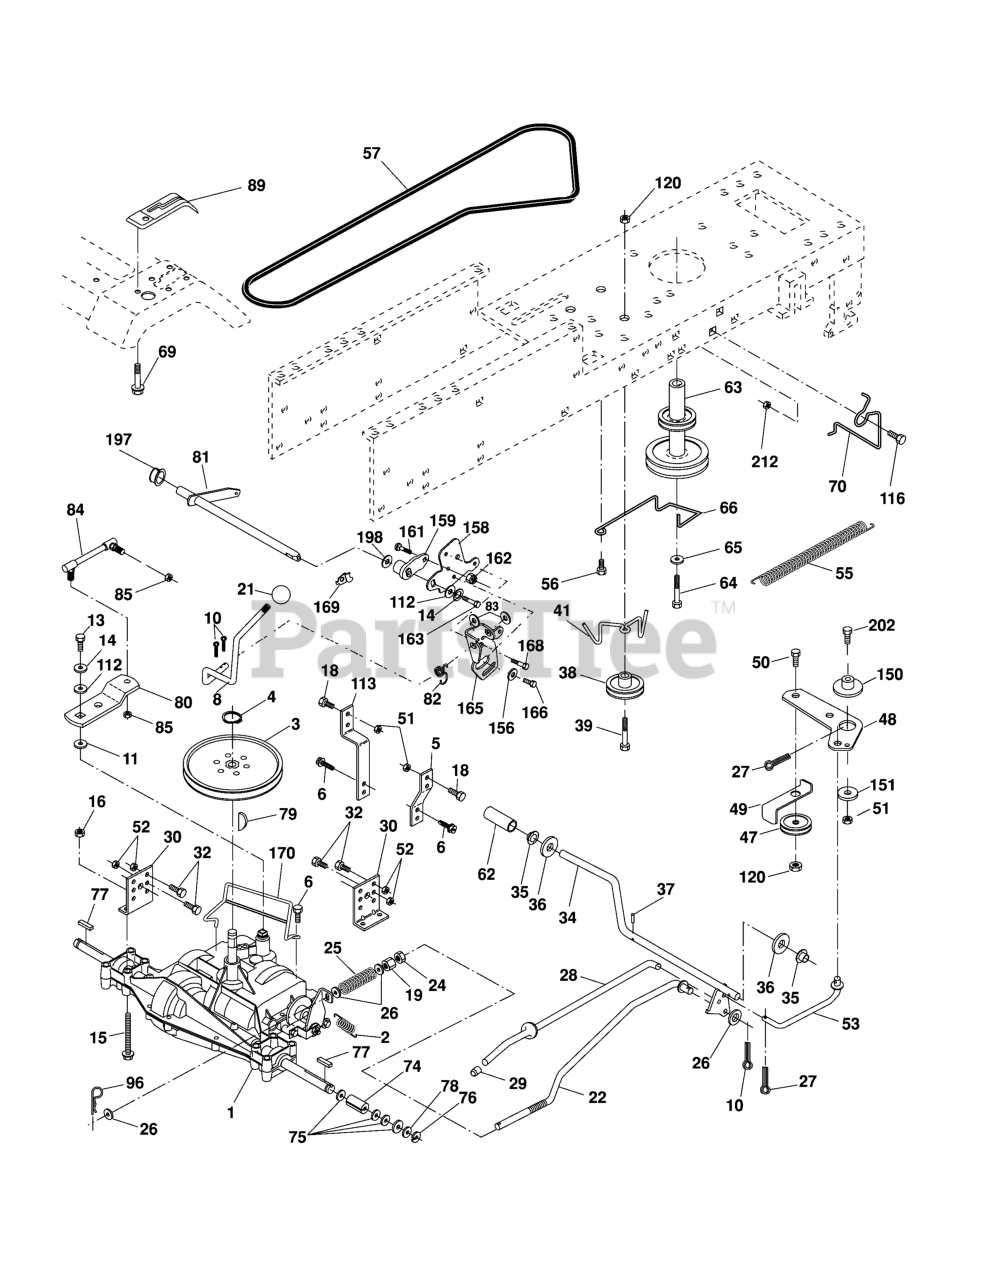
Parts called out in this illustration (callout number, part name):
2	Spring Return Brake
3	Pulley Transaxle 18" Tires
4	Ring Retainer # 5100-62
5	Strap Torque 30 Degrees RH
6	Screw 5/16-18 x 3/4
8	Rod Shifter Blk
10	Pin Cotter 1/8 x 1 Cad
11	Washer Plate Shf 388 Sq Hole
13	Bolt 1/4-28 unf Gr. 8 w/Patch
14	Washer Lock Hvy Helical 1/4
15	Bolt Hex Flghd 5/16-18 Gr. 5
16	Nut 5/16-18
18	Bolt Fin Hex 3/8-16 unc x 1 Gr. 5
19	Nut Lock Hex w/Ins 3/8-16 unc
22	Rod Brake LT
24	Nut Hex Jam 3/8-16 unc
25	Spring Rod Brake 2 00 Zinc
26	Washer 13/32 x 13/16 x 16 Ga.
27	Pin Cotter 1/8 x 3/4 Cad
28	Rod Brake Parking LT/YT
29	Cap Brake Parking
30	Bracket Transaxle
32	Bolt Fin Hex 5/16-18 x 3/4
34	Shaft Asm Pedal Foot Nibbed
35	Bearing Nylon Blk 629 Id
36	Washer 21/32 x 1 x 16 Ga.
37	Pin Roll 3/16 x 1"
38	Pulley Composite Flat
39	Bolt 3/8-16 x 2-3/4
41	Keeper Belt Idler
47	Pulley Idler V Groove Plastic
48	Bellcrank Clutch Grnd Drv STL
49	Retainer Belt Style Spring
50	Bolt Carr Sh 3/8-16 x 1-1/2 Gr. 5
51	Nut Crownlock 3/8-16 unc
52	Nut Crownlock 5/16-18 unc
53	Link Clutch
55	Spring Return Clutch 6 75
56	Screw 3/8-16 x 1-1/4
57	V-Belt Ground Drive 95.25
62	Cover Pedal Blk Round
63	Engine Pulley LT/YT
64	Bolt Hex 7/16-20 x 4 Gr. 5
65	Washer Lock Hvy Hlcl Spr 7/16
66	Keeper Belt Engine
69	Screw 1/4 x 1/2 unc
70	Guide Belt Mower Drive RH
74	Spacer Axle
75	Washer 25/32 x 1 1/4 x 16 Ga.
76	E-ring #5133-75
77	Key Square 2 0 x 1845/ 1865
78	Washer 25/32 x 1-5/8 x 16 Ga.
79	Key Woodruff
80	Arm Shift Transaxle
81	Shaft Asm Cross Taper
82	Spring Torsion Shift
83	Washer 17/32 x 3/4 x 16 Ga.
84	Link Transaxle
85	Nut Lock Center 1/4-28
89	Console Shift
96	Retainer Spring 1"
112	Washer 9/32 x 3/4 x 10 Ga.
113	Strap Torque 90 Degrees LH
116	Bolt Rdhd Sq Neck 3/8-16 x 1
120	Nut Lock Flg 3/8-16
150	Spacer Retainer Lt
151	Washer 13/32 x 2 x 10 Ga.
156	Washer Srrrtd 5/16 ID x 1.0 x .125
158	Bracket Shift Mount
159	Hub Shift
161	Bolt 1/4-20 x 3/4 Gr. 5
162	Nut Crownlock 1/4-20 unc
163	Bolt Hex Fin 1/4-20 unc x 1 Gr. 5
165	Bracket Pivot Lever
166	Screw 5/16-18 x 5/8
168	Bolt Shoulder 5/16-18 x .561
169	Plate Fastening
170	Keeper, Belt Transaxle
197	Nyliner Snap-In 5/8
198	Washer Nylon
202	Bolt Carr Sh 3/8-16 x 1-3/4 Gr. 5
212	Nut Hex Flg Lock
